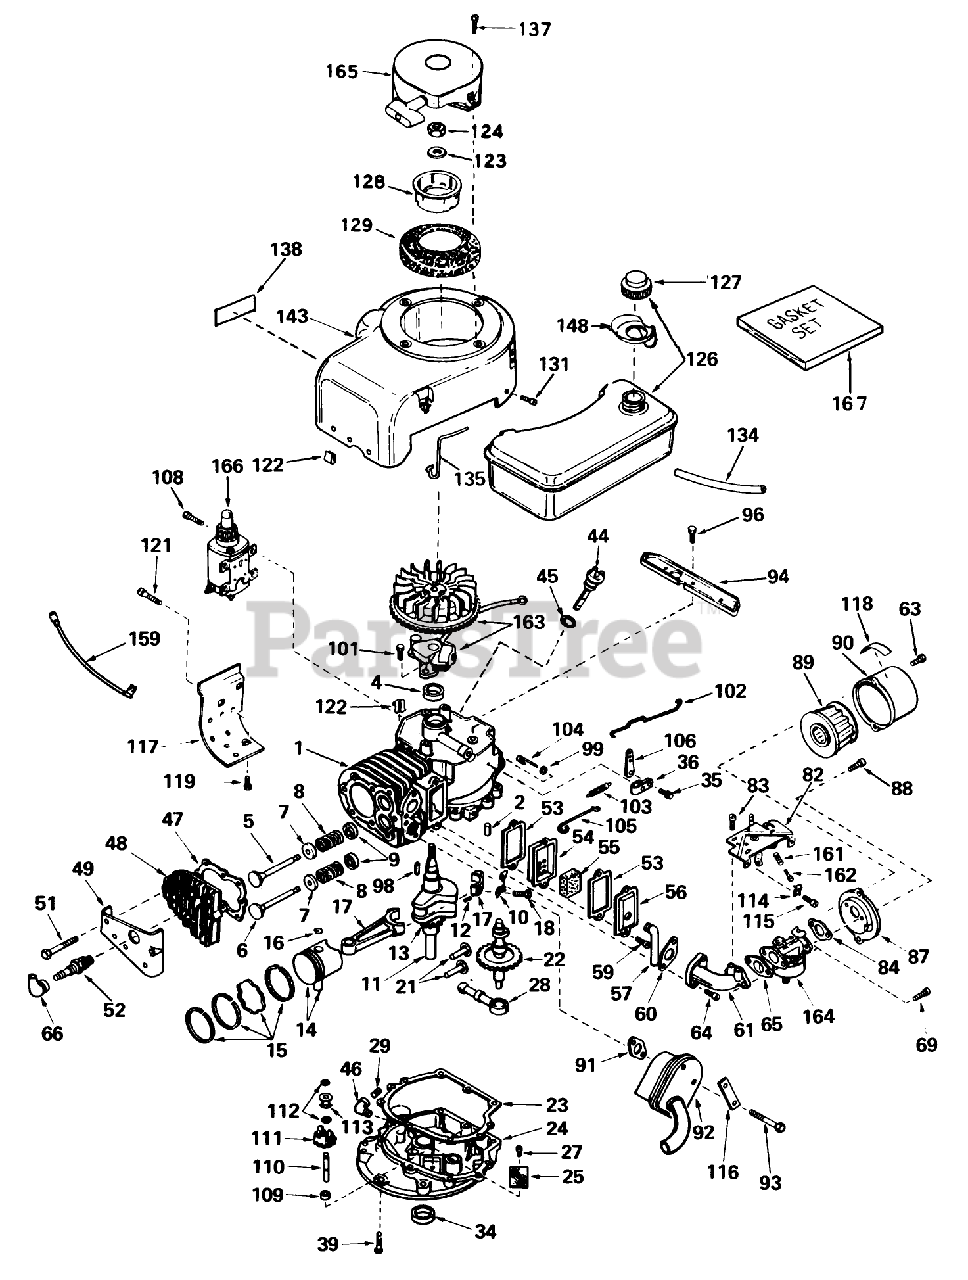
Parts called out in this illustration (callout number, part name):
1	Cylinder Assy. (Incl. Nos. 2, 4 44)
2	Pin-Dowel
4	Oil Seal
5	Valve, Intake (Standard)(Incl. No. 9)
5	Valve, Intake (1/32" oversize)(Incl. No. 9)
6	Valve, Exhaust (Standard)(Incl. No. 9)
6	Valve, Exhaust (1/32" oversize)(Incl. No. 9)
7	Cap-Spring, Valve
8	Spring-Valve
9	Keeper-Spring, Valve
10	Plate, Lock
11	Crankshaft Assy. (Incl. Nos. 12 13)(Model 935 only)
12	Pin, Groove
13	Gear-Crankshaft
14	Piston Pin Assy. (Incl. 2 of No. 16)(Standard)
14	Piston Pin Assy. (Incl. 2 of No. 16)(.010 oversize)
14	Piston Pin Assy. (Incl. 2 of No. 16)(.020 oversize)
15	ORing
15	Ring Set (.010" OS)
15	Ring Set (.020" OS)
17	Rod Assy., Connecting (Incl. Nos. 10 18)
18	Screw, Hex Hd.
21	Lifter-Valve
22	Screw
23	Gasket-Cover, Cylinder
24	Flange Assy., Mounting (Incl. Nos. 25, 27, 29, 34, 45 110)
25	Screen-Oil Filter
27	Screw
28	Pump, Oil
29	Plug-Drain, Oil (SQH 1/4-18)
34	Seal-Oil
35	Screw
36	Clamp-Lever, Governor
39	Screw (1/4-20 x 1-1/4)
44	Dipstick, Oil (Incl. No. 45)
45	Gasket
46	Elbow, 90
47	Gasket-Cylinder Head
48	CYLINDER HEAD
49	Cover-Head, Cylinder
51	Screw Hex Hd. Cap
52	Plug, Spark (J17LM or equiv.)
52	Plug, Spark (Champion RCJ-8)
53	Gasket-Breather
54	Body-Breather
55	Element-Breather
56	Cover-Valve
57	Tube-Breather
59	Screw
60	Gasket-Intake
61	Pipe-Intake
63	Screw
64	Screw (T-30, 5/16-18x1-3/32)
65	Gasket
66	Cover-Spark Plug
69	Screw-Hex Hd.
82	Control Assy., Speed (Incl. Nos. 161 162)
83	Screw (10-24 x 9/16)
84	Gasket
87	Bracket
88	Screw (10-32 x 1/2)
89	Element
90	Body
91	Gasket Exhaust
92	Muffler
93	Screw Hex Hd.
94	Bracket-Blower Housing
96	Screw (1/4-20x19/32)
98	Key-Flywheel
99	Washer-Flat
101	Screw
102	Link Governor
103	Spring Governor
104	Rod, Governor (Incl. Nos. 146)
105	Link Governor Spring
106	Lever-Governor
108	Screw
109	Spacer
110	Shaft, Governor
111	Governor Gear ASM
112	Ring-Retaining
113	Spool-Governor
114	Conduit
115	Screw (10-32 x 3/8)
116	62513 SNWTHWR W/284
117	Emnsion, Blower Housing
118	Decal
119	Screw
121	Screw
122	51004 GIL ROTARY TI
123	Washer
126	Tank Assy., Fuel (Incl. No. 127)
127	Cap, Fuel
128	Cup-Starter
129	Screen, Air
131	Screw, Hex Hd.
134	Line-Fuel (8.62)
135	Clamp, Tank Holdown
137	Screw
138	480B GIL SNWTHWR O/
143	Housing Blower
148	Deflector-Fuel
159	SPOOL RETAINER (10-PK)
161	Spring-Compression
162	Screw
163	Magneto
164	Carburetor
165	Starter, Rewind
166	Tine Shaft
167	Gasket Set
